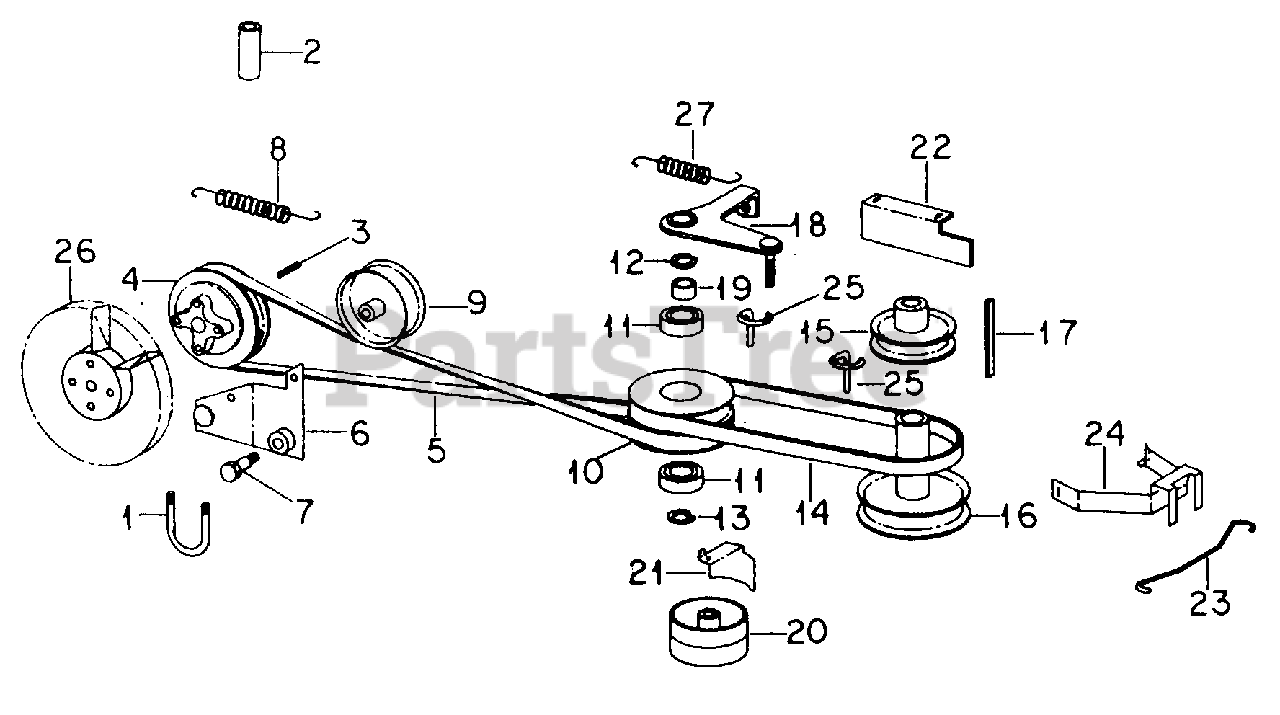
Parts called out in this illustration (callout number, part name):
2	Spacer, Transaxle Mounting
3	Key, 3/16 X 3/4 Woodruff No. 9
4	Pulley, Transmission Drive
5	Belt, Mower and Final Drive
6	Arm Assy, Belt Tensioning
7	Bolt, IPTO Shoulder
8	Spring, Extension, 5.5 In. Long, 48 Coils
9	Pulley, Final Drive Idler
10	Pulley, Intermediate Drive
11	Bearing, Intermediate Pulley
12	Ring, External Retaining
13	Ring, Internal Retaining
14	Belt, Clutching
15	Pulley, Hydro Engine Drive
16	Pulley, Mower Drive, 5-1/4 In. Diamter
17	Key, 1/4 X 2-3/4 Sq Parallel
18	Bushing Assy, Clutch
19	Bushing
20	Pulley, Mower Shifter Idler
21	Guide, Belt
22	Guide, Belt
23	Support, Belt Guide
24	Guide, Engine Belt
25	Guide, Transaxle Belt
26	Fan, Hydrostatic 6 Blade
27	Spring, Extension
